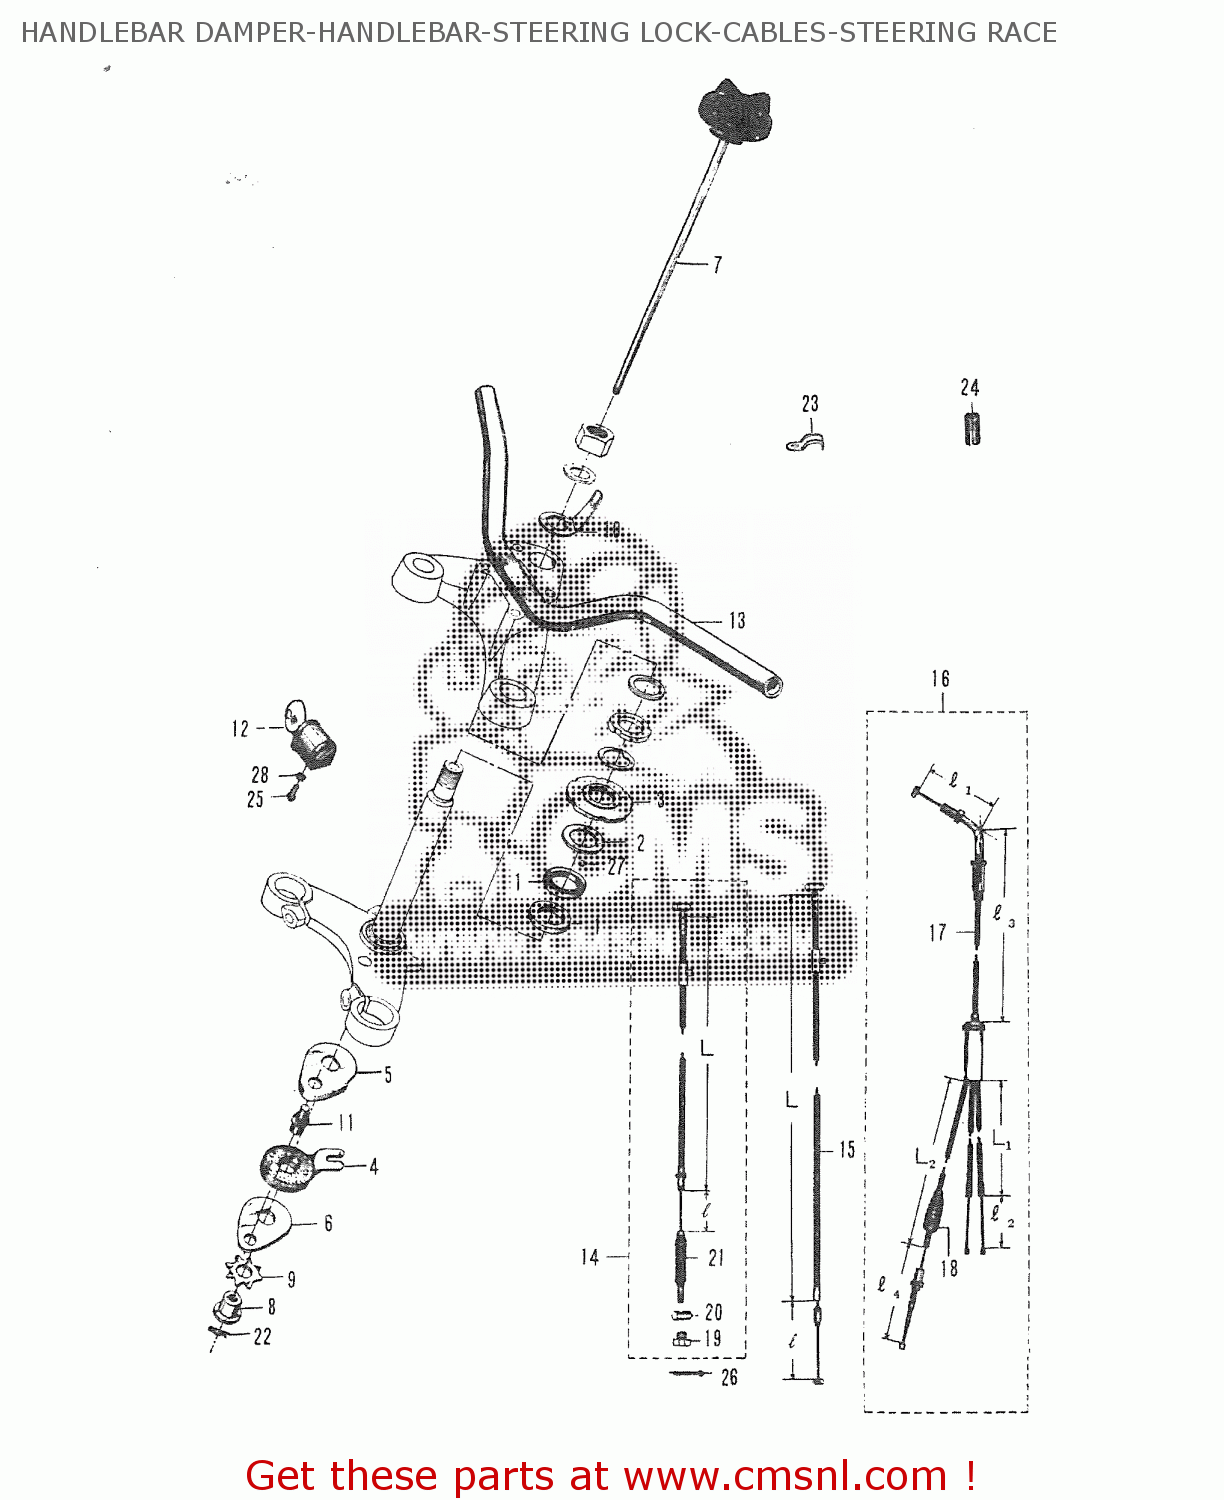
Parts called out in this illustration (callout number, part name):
1	RACE,STEERING,INNER,UPPER
2	RACE,STEERING,OUTER,UPPER
3	NUT,STEERING STEM
4	HANDLEBAR DAMPER CORK PLATE
5	PLATE,HANDLE DAMPER,UPPER
6	SPACER,STEERING DAMPER
7	HANDLEBAR DAMPER KNOB COMP.
8	HUB,HANDLEBAR DAMPER S
9	SPRING, DAMPER ADJUST
10	STOPPER, DAMPER KNOB
11	BRACKET,STEERING DAMPER
12	STEERING LOCK ASS'Y
13	HANDLEBAR
14	FRONT BRAKE CABLE ASS'Y
15	CLUTCH CABLE ASS'Y
16	CABLE ASSY,RR BRAKE
17	HANDLEBAR SIDE THROTTLE CABLE
18	DUST SEAL
19	NUT
20	PIN
21	SEAL,DUST
22	CLIP
23	CLAMP
24	CLIP
25	CROSS HAND SCREW
26	COTTER PIN
27	STEEL BALL
28	LOCK WASHER
